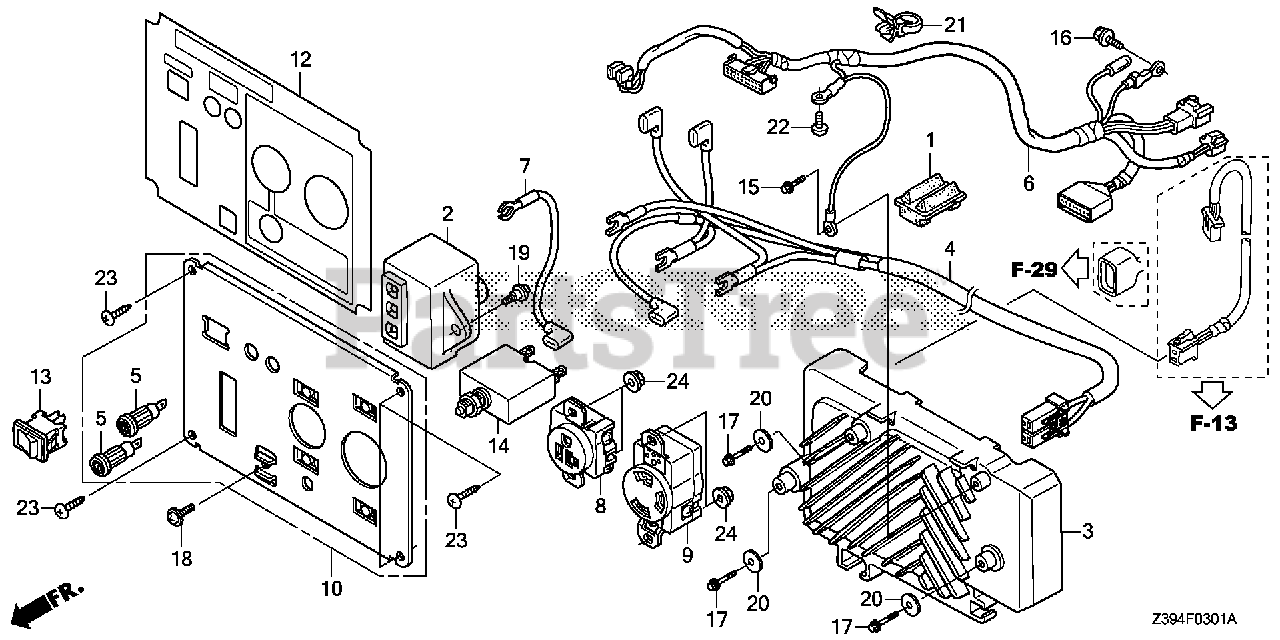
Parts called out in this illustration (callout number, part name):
1	RUBBER B, TANK MOUNTING
2	SPARK UNIT
3	INVERTER UNIT
4	SUB-WIRE HARNESS ASSY.
5	SOCKET, COMPOSITE
6	WIRE HARNESS ASSY., CONTROL
7	WIRE, TERMINAL
8	RECEPTACLE (20A/125V)
9	RECEPTACLE (30A/125V)
10	PANEL, CONTROL
12	MARK, CONTROL PANEL
13	SWITCH, AUTO-THROTTLE
13	SWITCH, AUTO-THROTTLE (OTAX)
14	PROTECTOR, CIRCUIT (20A) (WHITE)(TYCO)
14	PROTECTOR, CIRCUIT (20A) (BLACK)(JOEMEX)
15	BOLT, FLANGE (5X10)
16	BOLT, FLANGE (5X10) (CT200)
17	BOLT, FLANGE (5X12)
18	SCREW, PAN (5X12)
19	SCREW, PAN (5X13)
20	WASHER, PLAIN (20MM)
21	BAND (100MM) (BLACK)
22	SCREW, PAN (5X8)
23	SCREW, TAPPING (5X16) (PO)
24	NUT, FLANGE (4MM)
